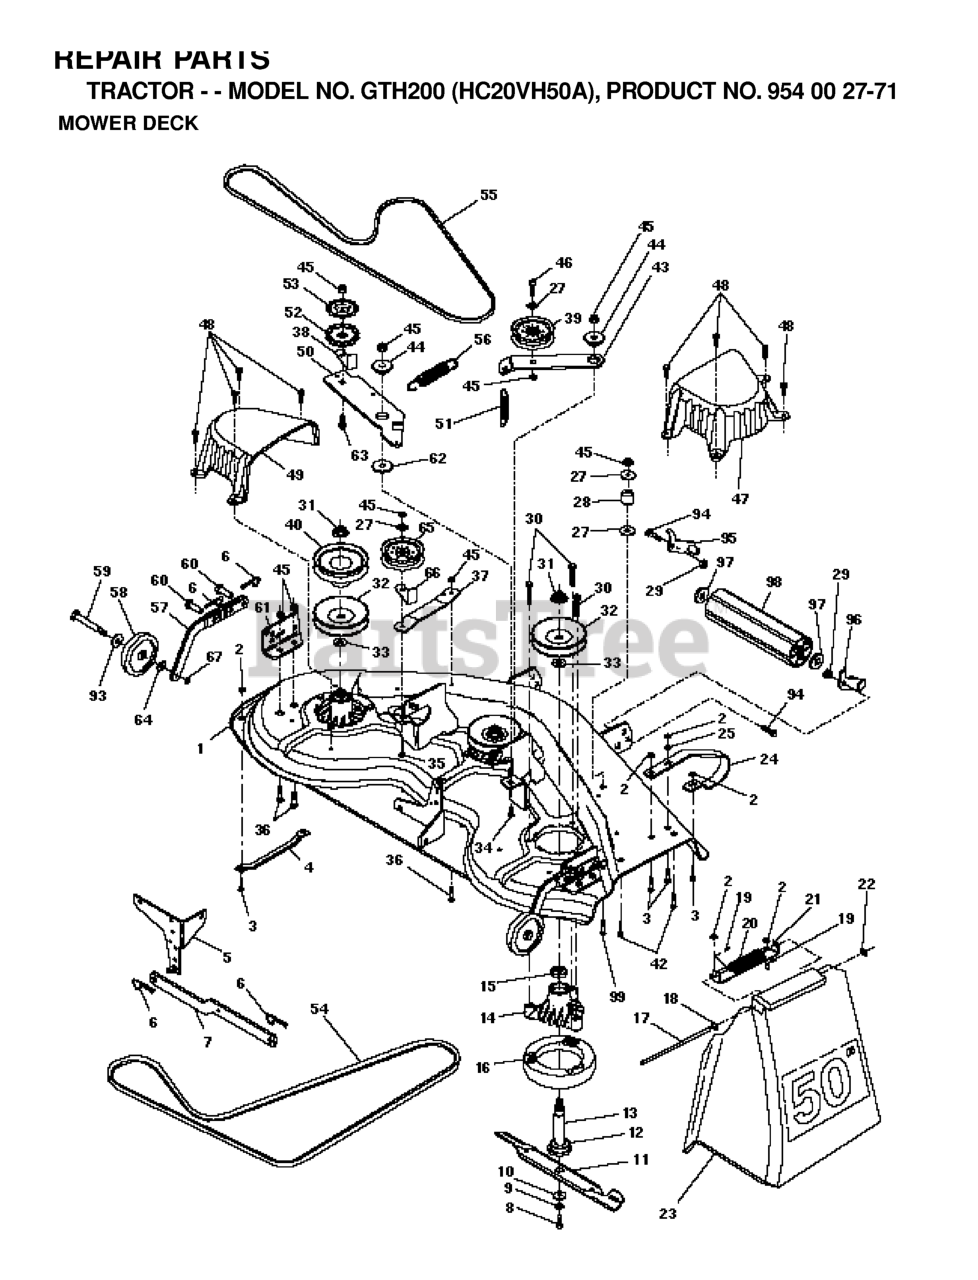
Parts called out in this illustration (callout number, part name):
1	DECK ASM MWR 50VT
2	LOCKNUT
3	BOLT.CARR.SQNK.5/16-18UNC.X3/4
4	RUNNER-LH M
5	BRACKET SWAY BAR
6	RETAINER-SPRNG RB
7	REAR SUSP ARM
8	BLADE BOLT
9	LOCKWASHER
10	WASHER.BLADE
11	BLADE.50".HI-LIFT
12	BEARING.BALL.#6204.(MANDREL)
13	SHAFT.ASM.W/BEARING
14	HOUSING.MANDREL.44/46" VENT
16	STRIPPER
17	ROD-HINGE T
18	Washer 11/32 x 5/8 x 16 Ga SD
19	CAP-SLEEVE LT
20	SPRING TORSION
21	BRACKET, DEFLECTOR
22	NUT PUSH M
23	SHIELD.DEFLECTOR.MOWER.50"BLK.
25	WASHER M
27	WASHER
28	IDLER SPRING SPACER
29	NUT
30	SCREW
31	NUT
32	MANDREL PULLEY
33	WASHER
34	BOLT.3/8-14X1.25
36	BOLT D
37	STIFFENER ARM
38	KEEPER
39	FLAT IDLER PULLEY
40	PULLEY.DRIVEN.44"
42	RP BOLT 5/16-18 X3/4 ZN/YEL GR
43	ARM.IDLER.SEC.44"
44	SPACER RETAINER
46	BOLT
47	COVER MANDRELL
48	SCREW.1/4-20X5/8
49	COVER.MANDREL.LH.44"
50	ARM.IDLER.PRIMARY
51	SPRING.SEC.44"VEN
52	PULLEY IDLER
53	SHIELD IDLER
54	V-BELT.PRMRY 46/50 VENT.BLK BK
55	BELT V SECONDARY
57	BAR.ASM.GUAGE.WHEEL
58	WHEEL.GAUGE.BLK.4.93
59	BOLT M
60	PIN.CLEVIS
61	BRACKET.GUAGE.WHEEL
62	HARDENED WASHER
63	BOLT.3/8-16X1.50
64	WASHER.5/16.FLAT.STE.STD.
65	IDLER-FLAT T
66	KEEPER
67	LOCKNUT
93	Washer 17/32 x 15/16 x 12 Gauge
94	BOLT
95	BRACKET LH (A)
96	BRACKET RH (B)
97	Washer 1 17/32 X 7/8 X 16 Ga
98	NOSE ROLLER
